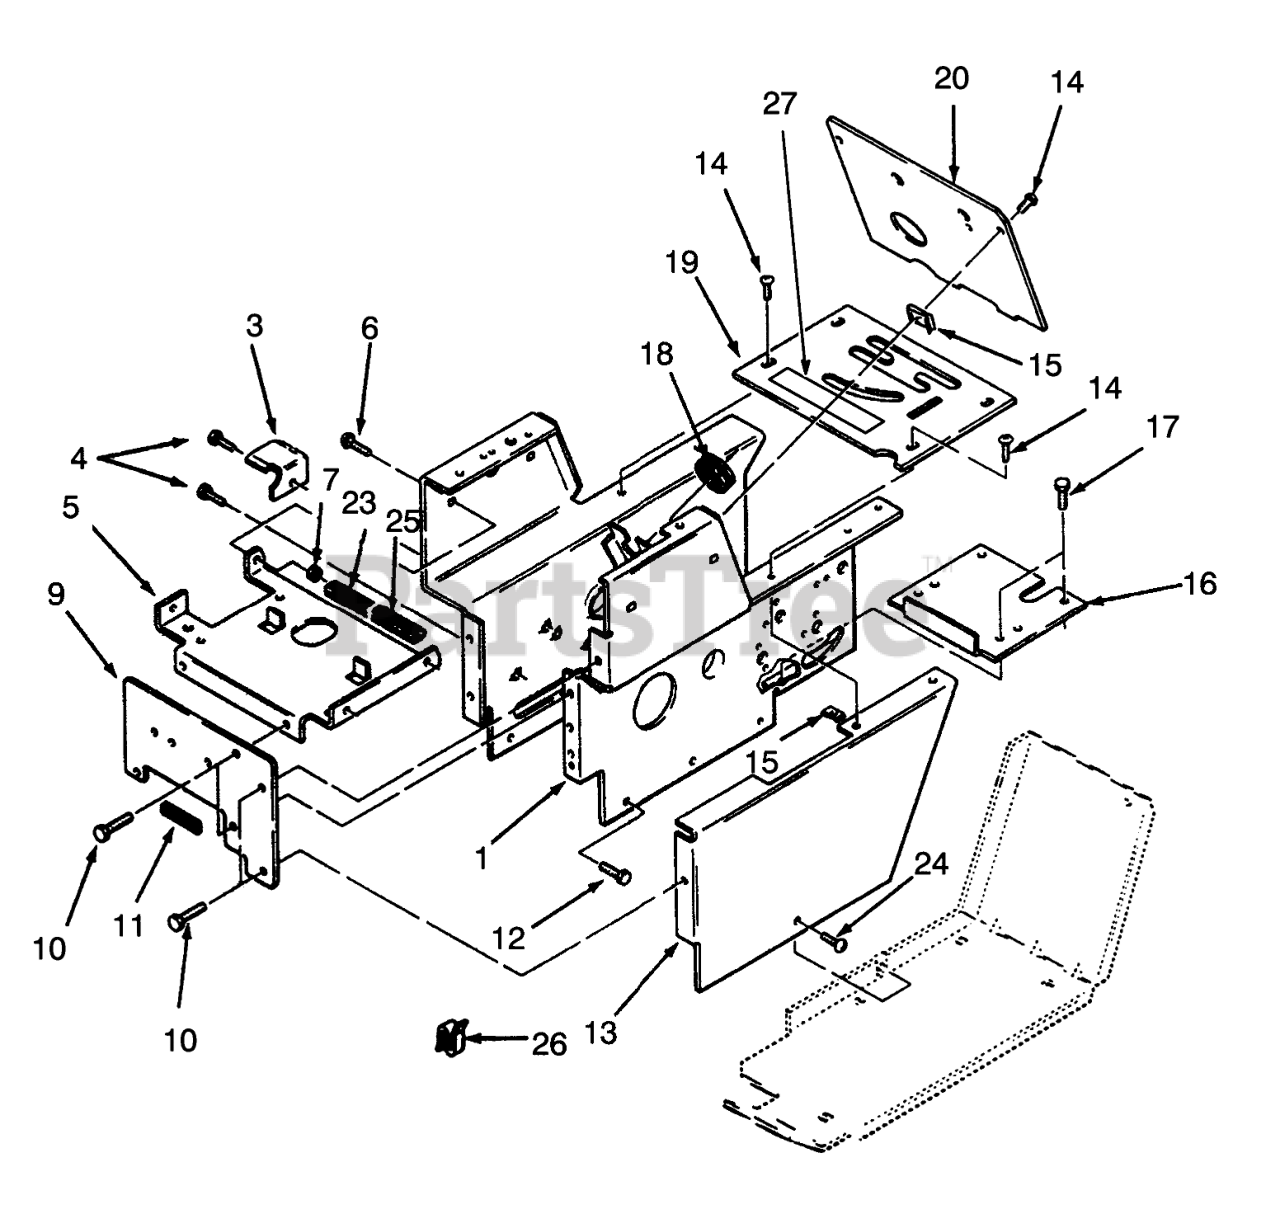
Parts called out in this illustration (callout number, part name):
1	Handstand
3	Belt Bracket
4	SCREW
5	SUPORT-BATERYB
6	BOLT CARR. 5/16X1/2 BK
7	Nut
9	Front Plate
10	SCREW
11	EDGE TRIM 4IN OF 102896
12	SCREW
13	Cover-Side LH
14	Screw
16	Cover-Dust
17	SCREW
18	GROMMET
19	Plate-Shift Cover (Incl. Ref. #27)
20	Plate-Hood Stand
23	EDGE TRIM 5" OF 102896
24	Screw
25	EDGE TRIM 2" 102896
26	SPEED CLIP
27	DECAL-DANGER
